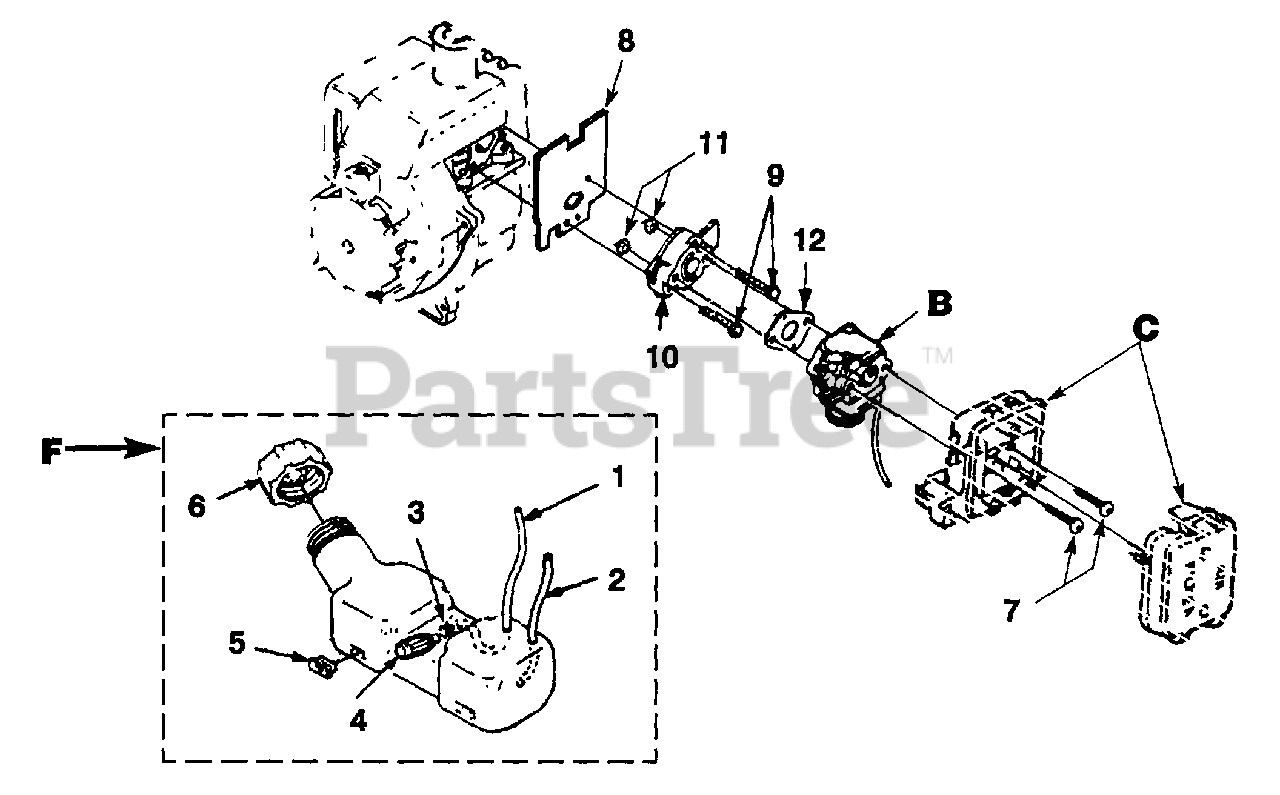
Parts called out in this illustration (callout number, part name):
1	TUBING-Rubber (4 1/4")
2	TUBING-Rubber (7 1/2")
3	CLAMP-Wire
4	FILTER-Fuel
5	BUMPER-Rubber
6	CAP-Fuel Tank
7	SCREW-Sems Hex Hd. (10-24 X 2 1/2")
8	GASKET-Heat Dam
9	SCREW-Sems, Torx (10-24 X 1.12")
10	HEAT DAM
11	NUT-Hex (10-24)
12	GASKET-Carburetor
F	FUEL TANK
B	CARBURETOR (Zama)
